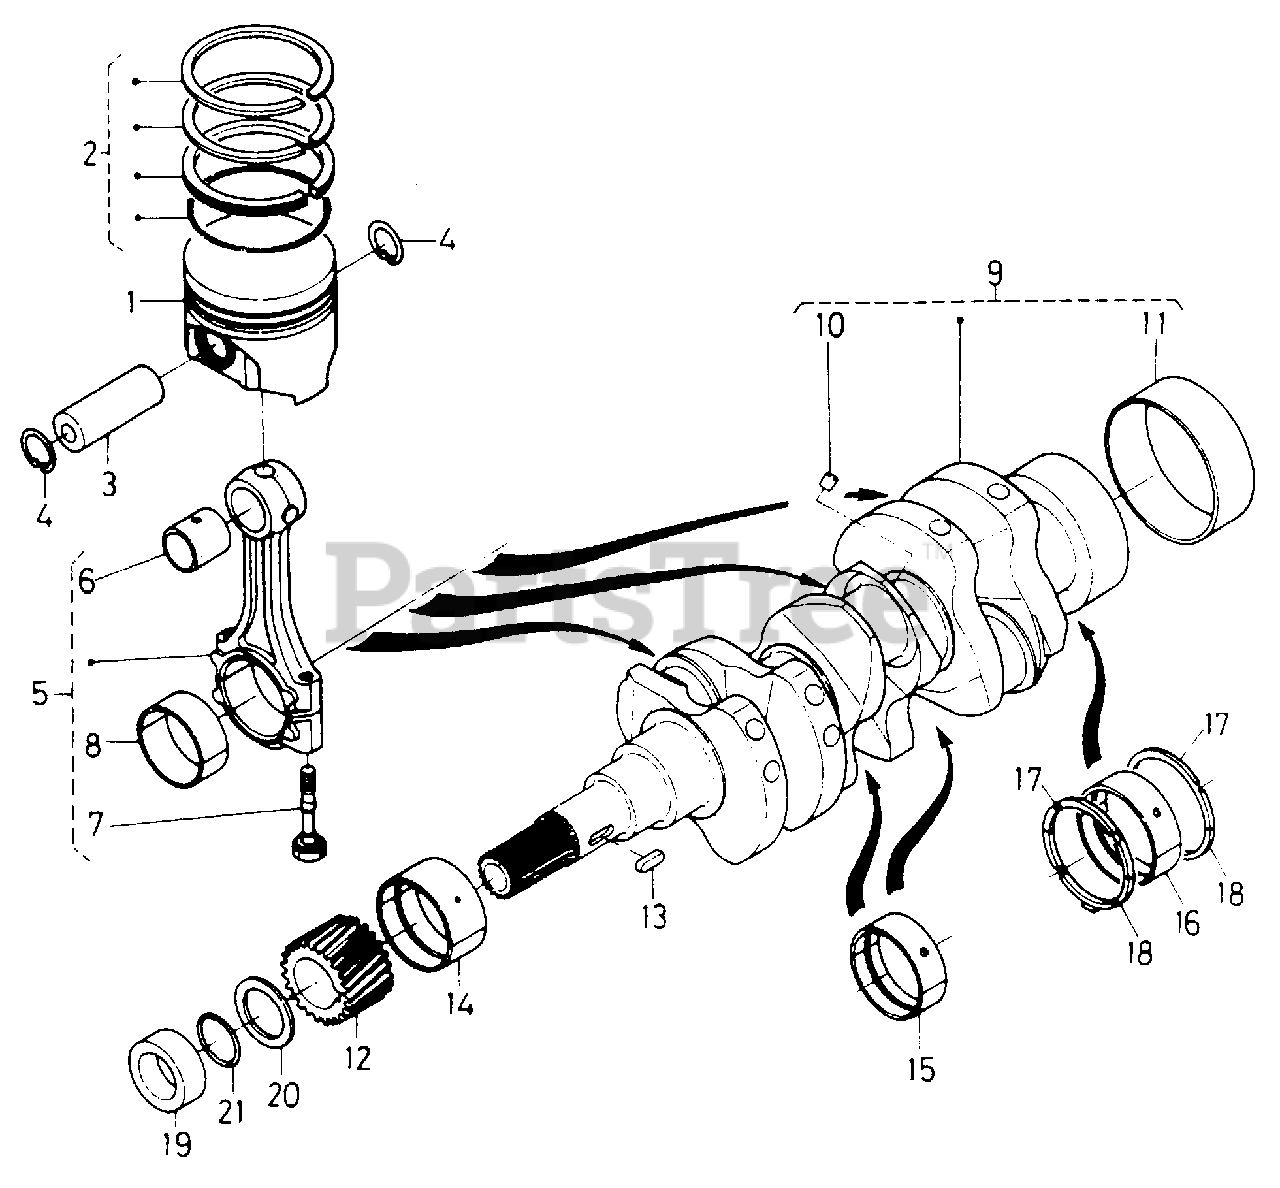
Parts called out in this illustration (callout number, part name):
2	Ring, Piston (Std)
4	Ring, Retaining
5	Rod Assy, Connecting
6	Bushing, Piston Pin
7	Bolt, Connecting Rod
8	Bearing, Connecting Rod (Std)
9	Crankshaft Assy
11	Sleeve, Crankshaft
12	Gear, Crankshaft
14	Bearing, Crankshaft Main (Std)
15	Bearing, Crankshaft Main (Std)
16	Bearing, Crankshaft Main (Std)
17	Bearing, Side (Std)
18	Bearing, Side (Std)
19	Collar, Crankshaft
20	Slinger, Crankshaft Oil
